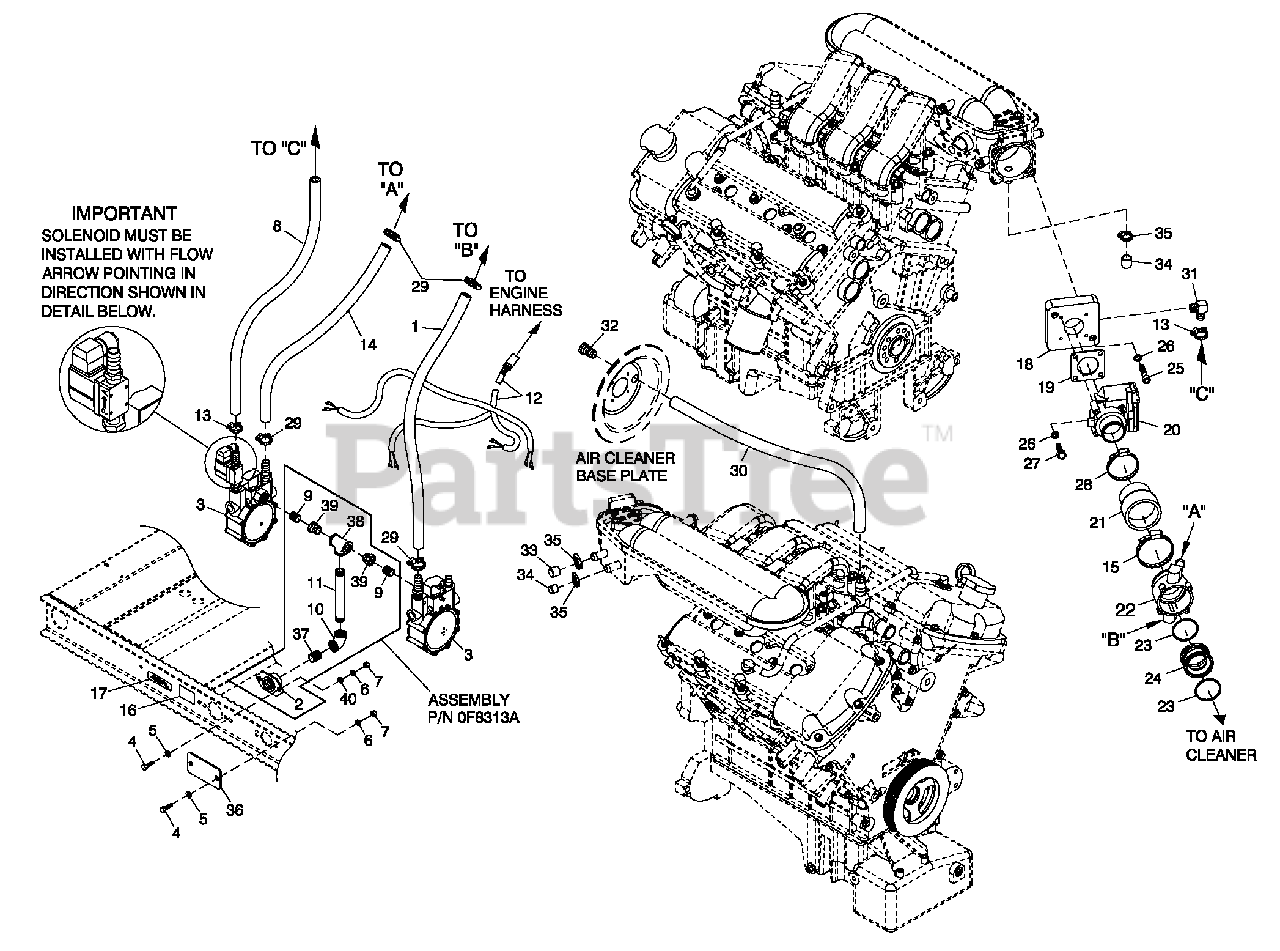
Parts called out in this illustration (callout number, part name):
1	HOSE 3/4 ID SAE-30R2 (24"LG)
2	FLANGE FUEL INLET
3	ASSYREGULATR60KWNG
4	SCREW HHC #8-1.25X20 G8.8
5	WASHER FLAT 5/16-M8 ZINC
6	WASHERLOCK M8-5/16
7	NUT HEX M8-1.25 G8 CLEAR ZINC
8	HOSE 3/8 ID SINGLE BRAID (18" LG)
9	NIPPLE CLOSE 3/4X1.375
10	ELBOW 90D1-1/4 NPT
11	NIPPLE PIPE 1.25 NPT X 5.5 BLIRN
12	HARNESS FUEL JUMPER DUAL REG
13	CLAMP HOSE #8 .53-1.00
14	HOSE 3/4 ID SAE-30R2 (27" LG)
15	CLAMP HOSE #44 2.31-3.25
16	DECAL INLET PRESSURE
17	DECAL FUEL INLET NG
18	INTAKE ADAPTER BOSCH
19	GAS KET BOSCH 32 & 40
20	ACTUATOR BOSCH 40 GOVERNOR
21	REDUCER RUBBER 3.0"-2.00"
22	MIXER 40/60MM ACTUATOR ASSY
23	O-RING 2-3/4X3/32X2-15/16
24	VENTURI THROTTLE 32MM
25	SCREW SHC M6-1.0 X 25 G12.9 ZP
26	WASHER LOCK M6-1/4
27	SCREW HHC M6-1.0X 50 G8.8
28	CLAMP HOSE #36 1.88-2.75
29	CLAMP HOSE #10 .56-1.06
30	HOSE COOL 5/8"ID 250#WP (24"LG)
31	BARBED EL 901/4NPTX 3/8
32	ADAPTER INSERT HOSE BARB 5/8"
33	CAP VINYL .5" ID X 1.0" DPBLK
34	CAP VINYL 3/8" ID X1" DP BLK
35	CLAMP HOSE .38-.87
36	COVER FUEL INLET LP
37	NIPPLE CLOSE 1.25 NPT X 1.625
38	PIPE TEE 1-1/4 NPT
39	BSHG RDCR HEX1-1/4-3/4
40	WASHER FLAT 3/8 ZINC
